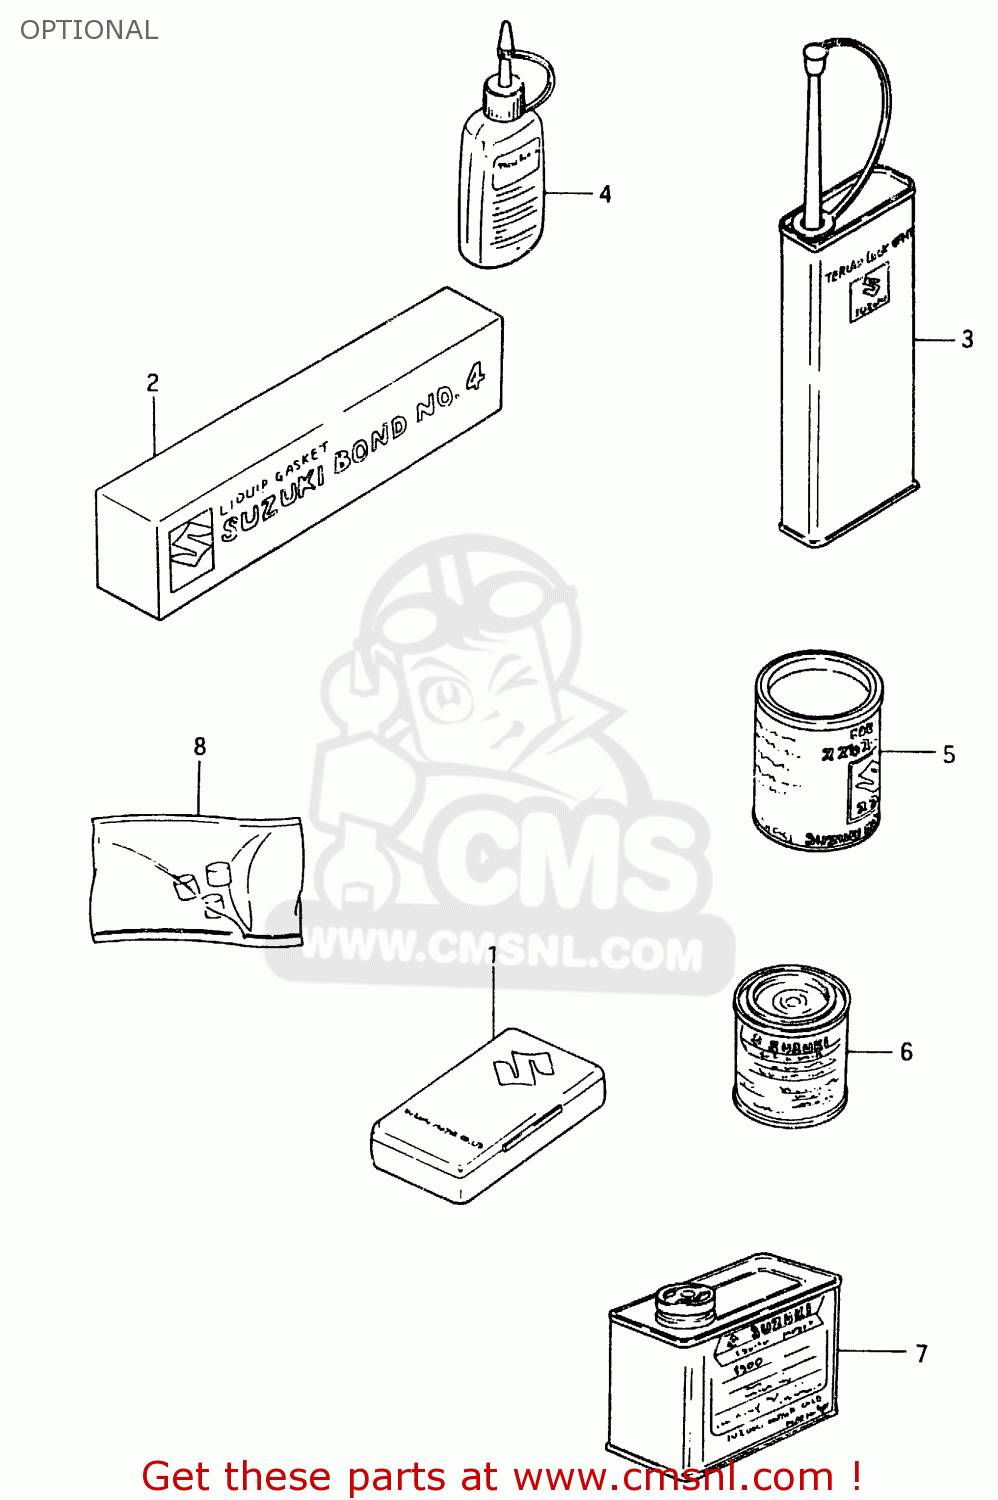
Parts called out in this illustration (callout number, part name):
1	TUBE REPARING TOOL
2	BOND 1104
3	THREAD LOCK NO.1401 CLEAR 200G
4	** SUPERSEEDED
5	GREASE(C)EP2 LITHIUM 150G
6	ANTI-LEAK ADDITIVE
